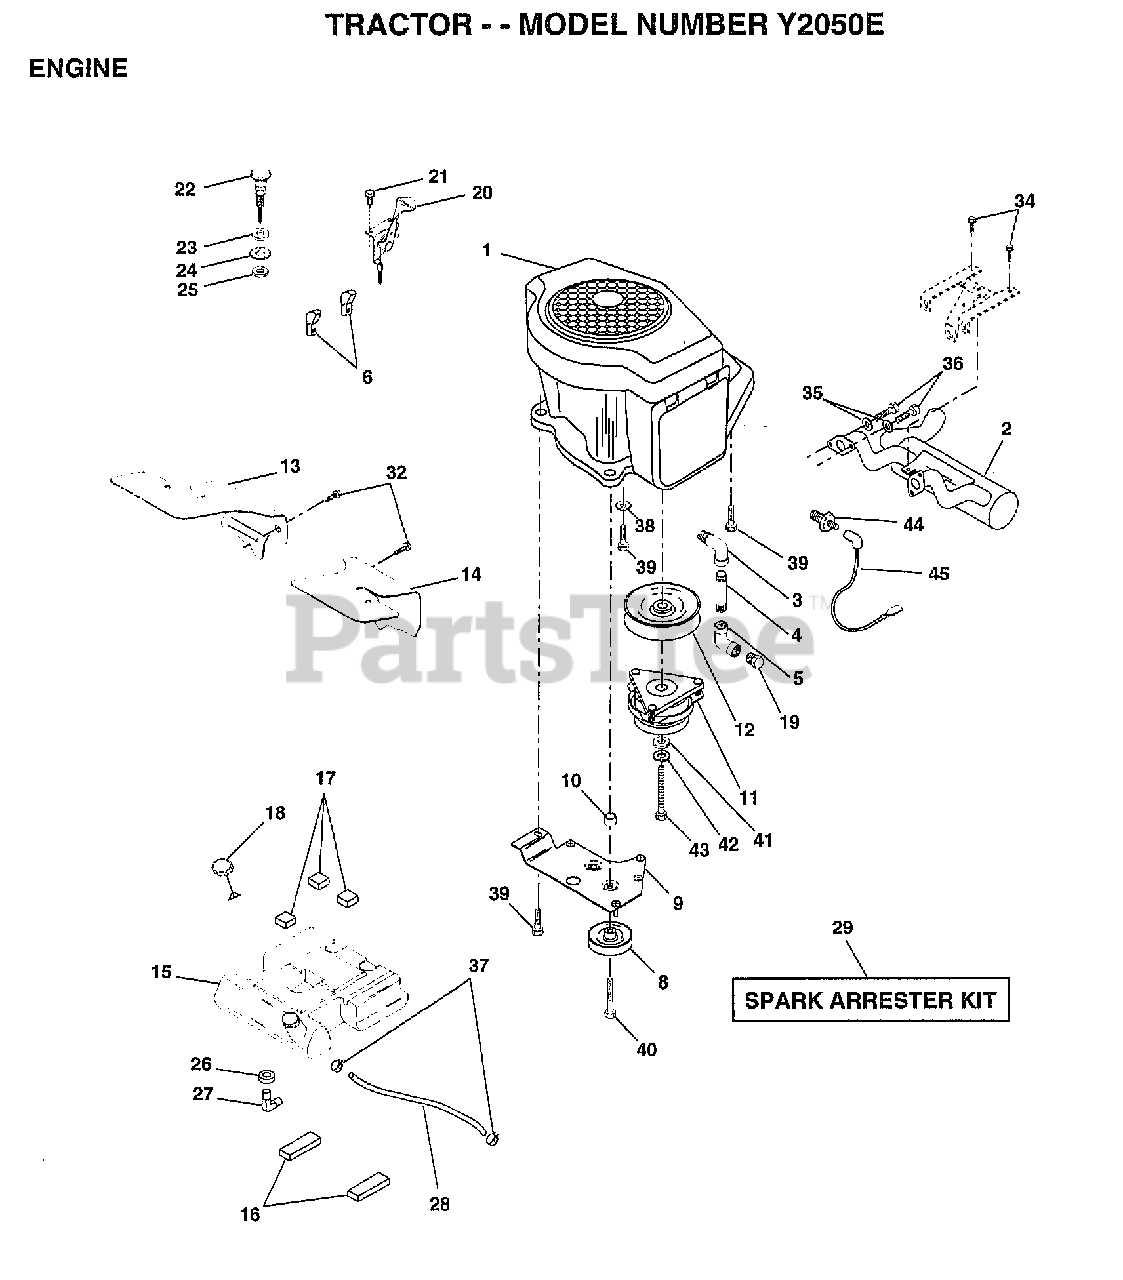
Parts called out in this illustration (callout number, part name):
2	MUFFLER.KOH.VCT.
3	STREET ELBOW LT
4	PIPE NIPPLE
5	ELBOW
6	CLAMP.TUBE.DBL.EN
10	BUSHING.
12	PULLEY.ENGINE.VGT
13	BAFFLE.AIR.LH.K
16	PAD IDLER TI
17	PAD-SPACER LT
18	CAP ASM FUEL
19	PLUG T
20	CONTROL THTL 37
21	SCREW LT
22	"CONTROL.CHOKE.51"""
23	WASHER
24	LOCKWASHER
26	BUSHING OUTLET T
27	STEM.TANK.FUEL
29	SPARK ARREST KIT
32	SCREW LT
34	SCREW
35	LOCKWASHER
36	SCREW
37	HOSE CLAMP
38	LOCKWASHER
39	SCREW LT
40	SCREW.3/8-16X3.25
41	WASHER
42	LOCKWASHER
44	SWITCH OIL KOHLER
45	WIRE LEAD KOHLER
